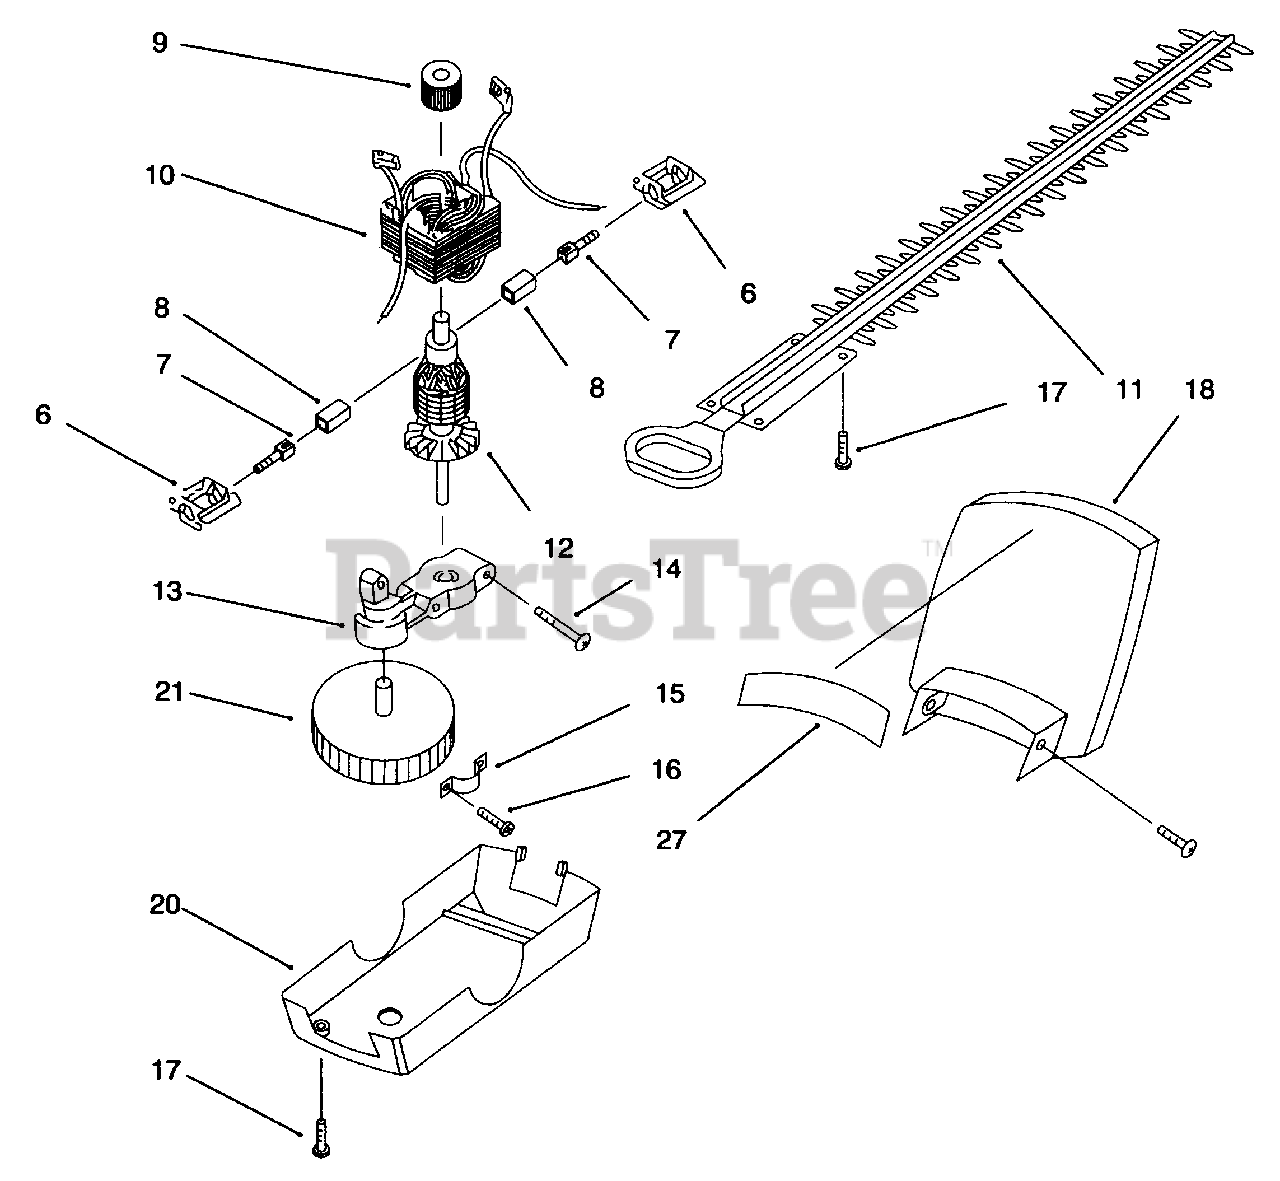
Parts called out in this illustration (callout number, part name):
6	BRUSH TUBE HOLDER
7	BRUSH ASSEMBLY
8	BRUSH TUBE
9	HEAT SINK W/BEARING
10	FIELD ASSEMBLY
11	BLADE ASSEMBLY (51815)
12	ARMATURE
13	BEARING PLATE W/BEARINGS
15	BEARING STRAP
18	BLADE GUARD
20	BLADE COVER
